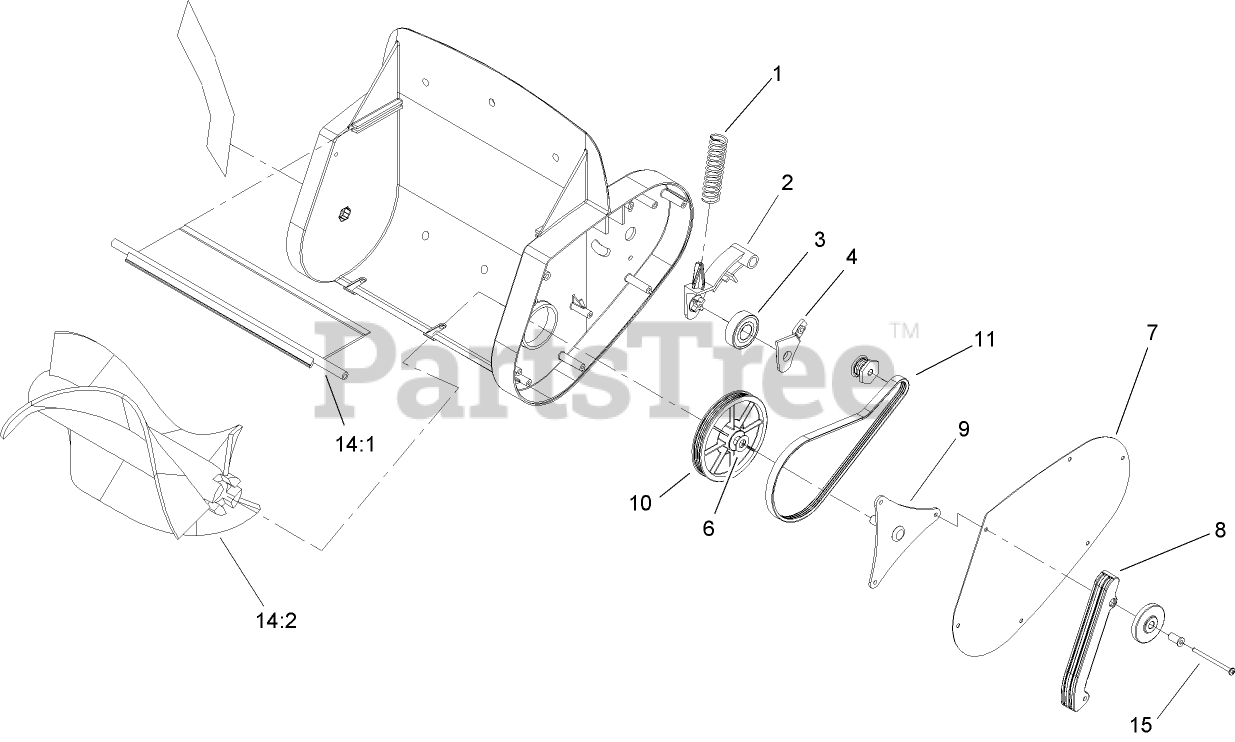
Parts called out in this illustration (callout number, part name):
1	SPRING
2	ARM-IDLER
4	RETAINER-PULLEY, IDLER ARM
6	WASHER-THRUST
7	PLATE-SIDE
8	SCRAPER-LEFT, SWEEP
9	PULLEY BRACKET ASM
10	PULLEY ASM
11	BELT-DRIVE
14	Loose Parts Package
14:1	DEFLECTOR AND DECAL ASM
14:2	BRUSH-ROTOR
15	SCREW-PPH
